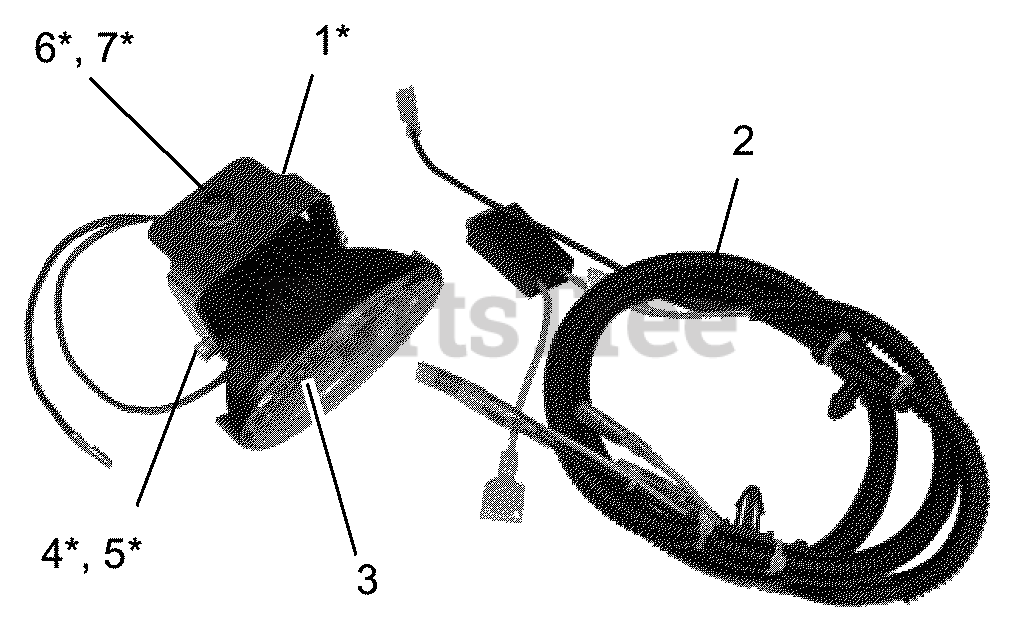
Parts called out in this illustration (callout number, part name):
1	WMT, LIGHT BRACKET
2	HARNESS,MINI-Z HEADLIGHT
3	LIGHT-CONS RIDE ON- SEE B-2124
4	WSHR-LK 4MMX1MM REG CL ZINC
5	SCREW-M4X.07X8 SHCS CLZNC
6	@WSHR-LK .31X.078 REG YWZC
7	SCR-CAP BTHD.31-18X.50 GR5 YZ
